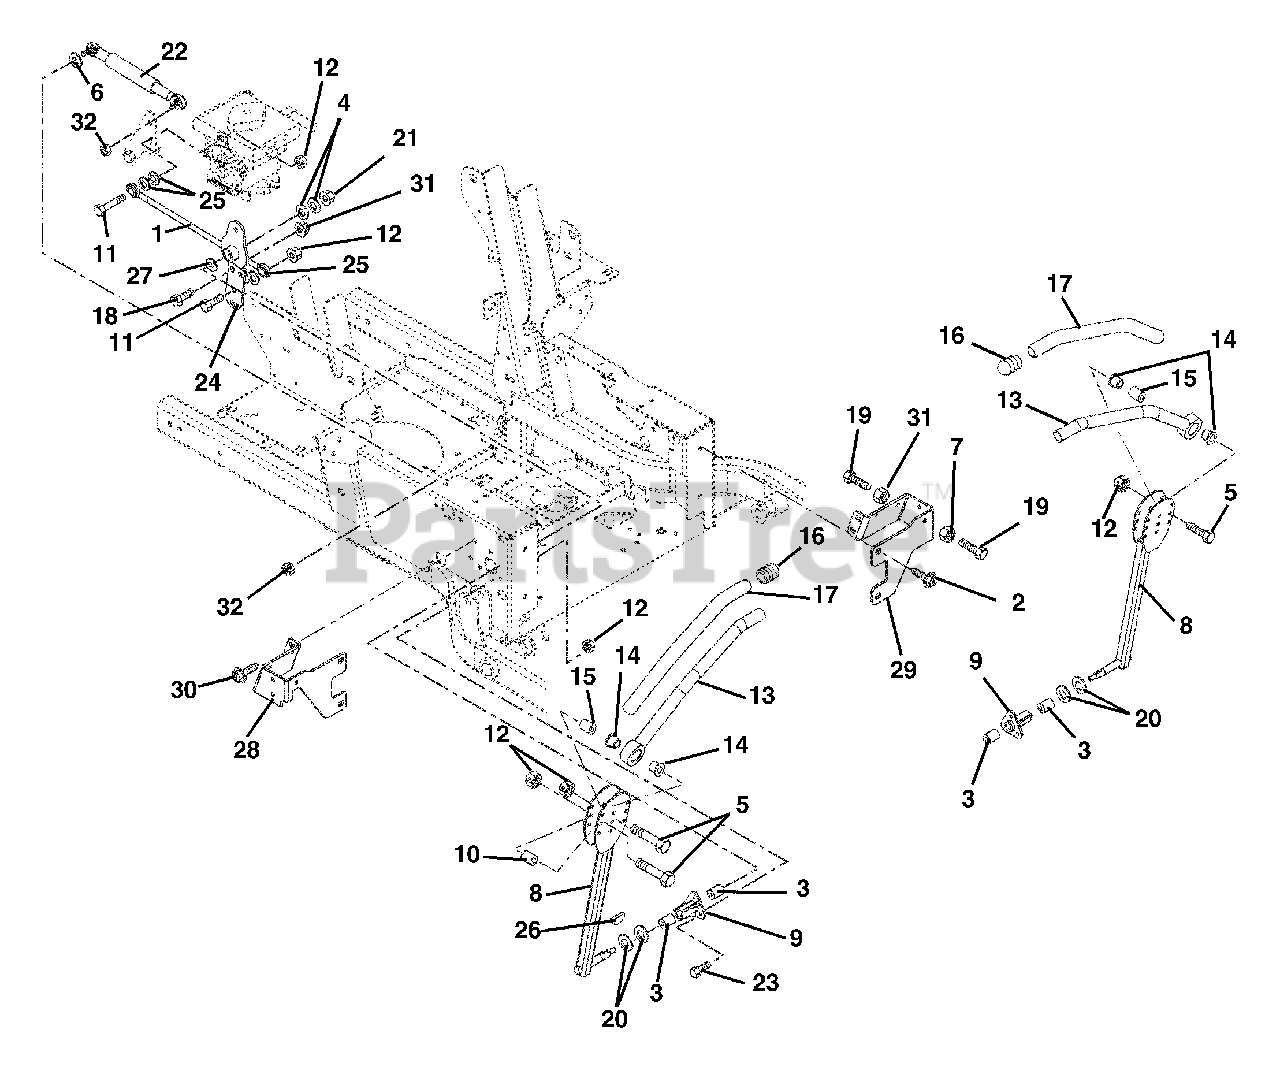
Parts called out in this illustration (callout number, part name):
1	ASSY, STEERING ROD
2	@SCR-TAP .38-16X.75 HWH TR YWZ
3	BSHG .625X.750X.500
4	@WSHR-FL-STL.38X.875X.083 YWZC
5	@BLT-HEX .31-18X1.75 GR5 YWZC
6	@WSHR-FL-STL.344X.688X.065YWZC
7	NUT-HEX-JAM .375-16 YWZC
8	CONTROL ARM - BLACK
9	BUSHING, FLANGE
10	ECCENTRIC
11	@BLT-HEX .31-18X1.25 GR5 YWZC
12	@NUT-LK-TOP-FLG .31-18 YWZC
13	HANDLE WLDMT LH
14	BSHG-FLG .762X1.48X.44 NYL
15	SPACER .328 X .76 X 1.01
16	CAPLUG - HANDLEBAR
17	GRIP - HANDLEBAR
18	BLT-HEX .375-16X1.750 FTD YWZC
19	@BLT-HEX .38-16X1.25 GR5 YWZC
20	WSHR-FL-STL .630X1.005X.062 YZ
21	@NUT-LK-TOP-FLG .38-16 YWZC
22	DAMPENER
23	@BLT-HEX .31-18X.75 GR5 YWZC
24	ARM, PIVOT
25	@WSHR-LK .31X.078 REG YWZC
26	KEY-WDRF .13X.63 HRD#5
27	WAVE WASHER .640X.875X.125FH
28	STOP, STEERING-RH (BLACK)
29	STOP, STEERING -LH (BLACK)
30	@SCR-TAP .38-16X.50 HWH TR YWZ
31	@NUT-LK-CTR-JAM .375-16 YWZC
32	@NUT-LK-NYL M8-1.25 YWZC
